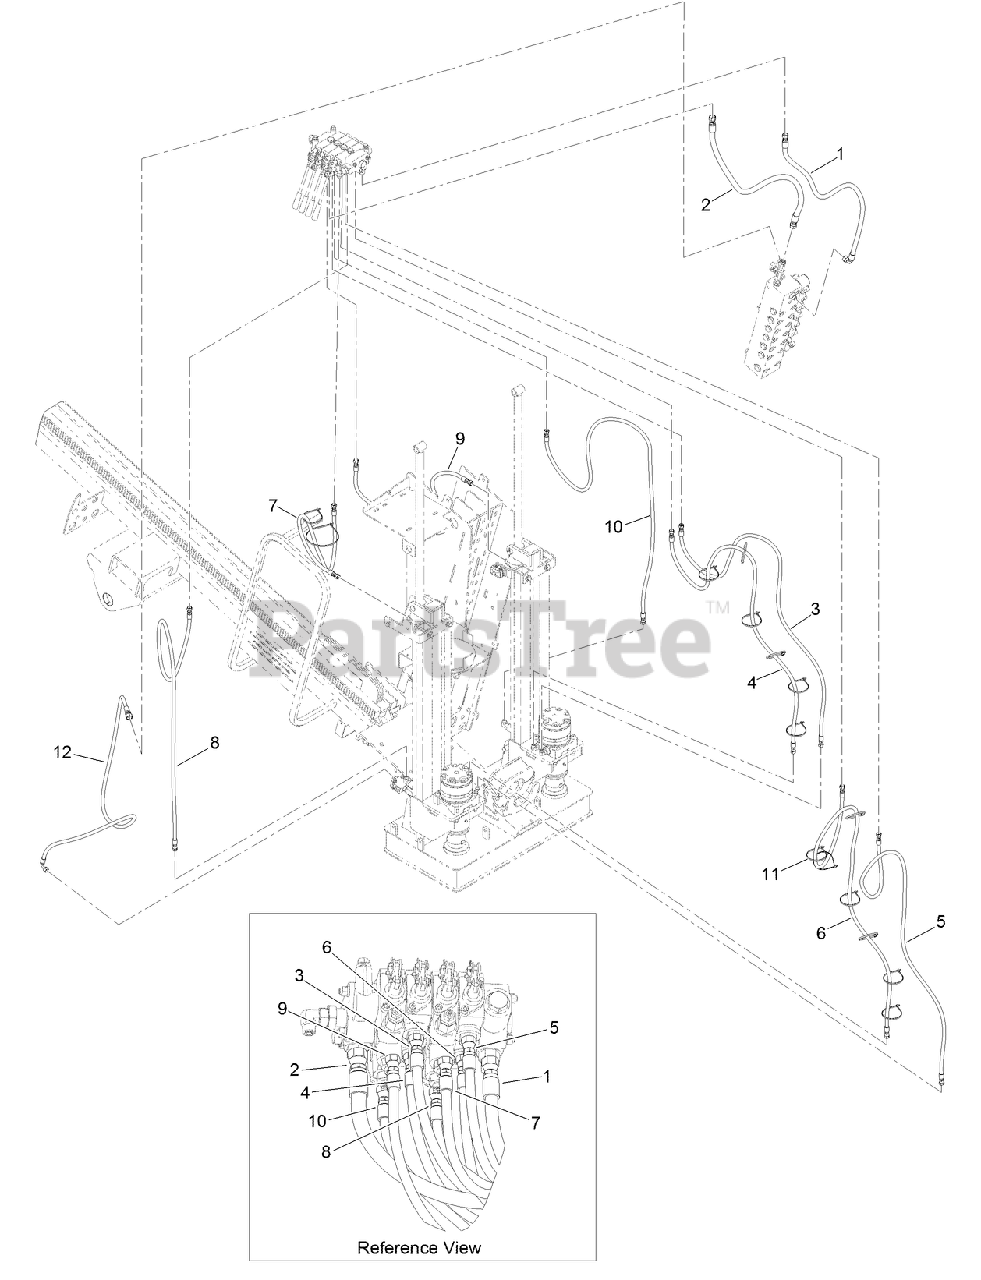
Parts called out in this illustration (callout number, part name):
1	HOSE ASM
2	HOSE ASM
3	HOSE ASM
4	HOSE ASM
5	HOSE ASM
6	HOSE ASM
7	HOSE ASM
8	HOSE ASM
9	HOSE ASM
10	HOSE ASM
11	TIE-CABLE
12	HOSE ASM
